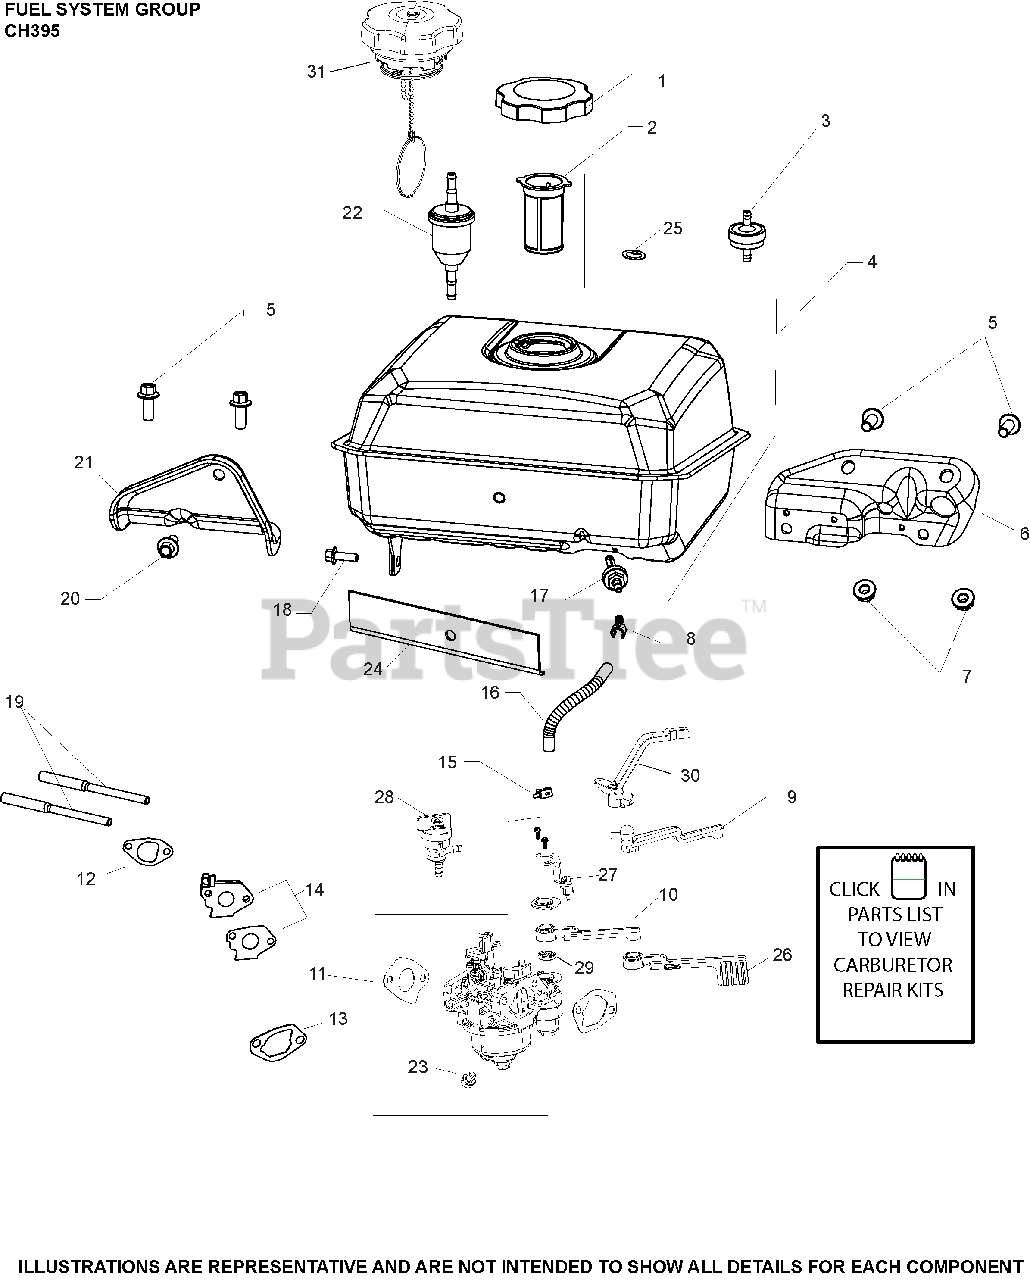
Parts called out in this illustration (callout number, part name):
2	FILTER, FUEL TANK
4	TANK, FUEL ASSY
5	SCREW, M8 X 20
7	NUT, FLG M8X1.25
8	CLIP, FUEL HOSE
11	KIT, CARBURETOR COMPLETE
13	GASKET, AIR CLEANER
14	INSULATOR AND GASKET KIT
15	CLAMP, FUEL LINE
16	LINE, FUEL (10"-CUT TO LENGTH)
17	FITTING, FUEL ASSY
18	SCREW, M6 X18
19	STUD, CARBURETOR
20	SCREW, FLG 8X1.25X16
21	BRACKET, FUEL SUPPORT
25	KIT, FUEL SCREEN
29	SEAL, INLET VALVE
31	CAP, EVAPORATIVE EMISSIONS
1775507-S	KIT, HIGH ALTITUDE (4,000-8,000 FT)
1775521-S	KIT, HIGH ALTITUDE (ABOVE 8,000 FT.)
1775703-S	KIT, CARBURETOR REPAIR
17126245-S	BRACKET, FUEL SUPPORT ASSEMBLY
